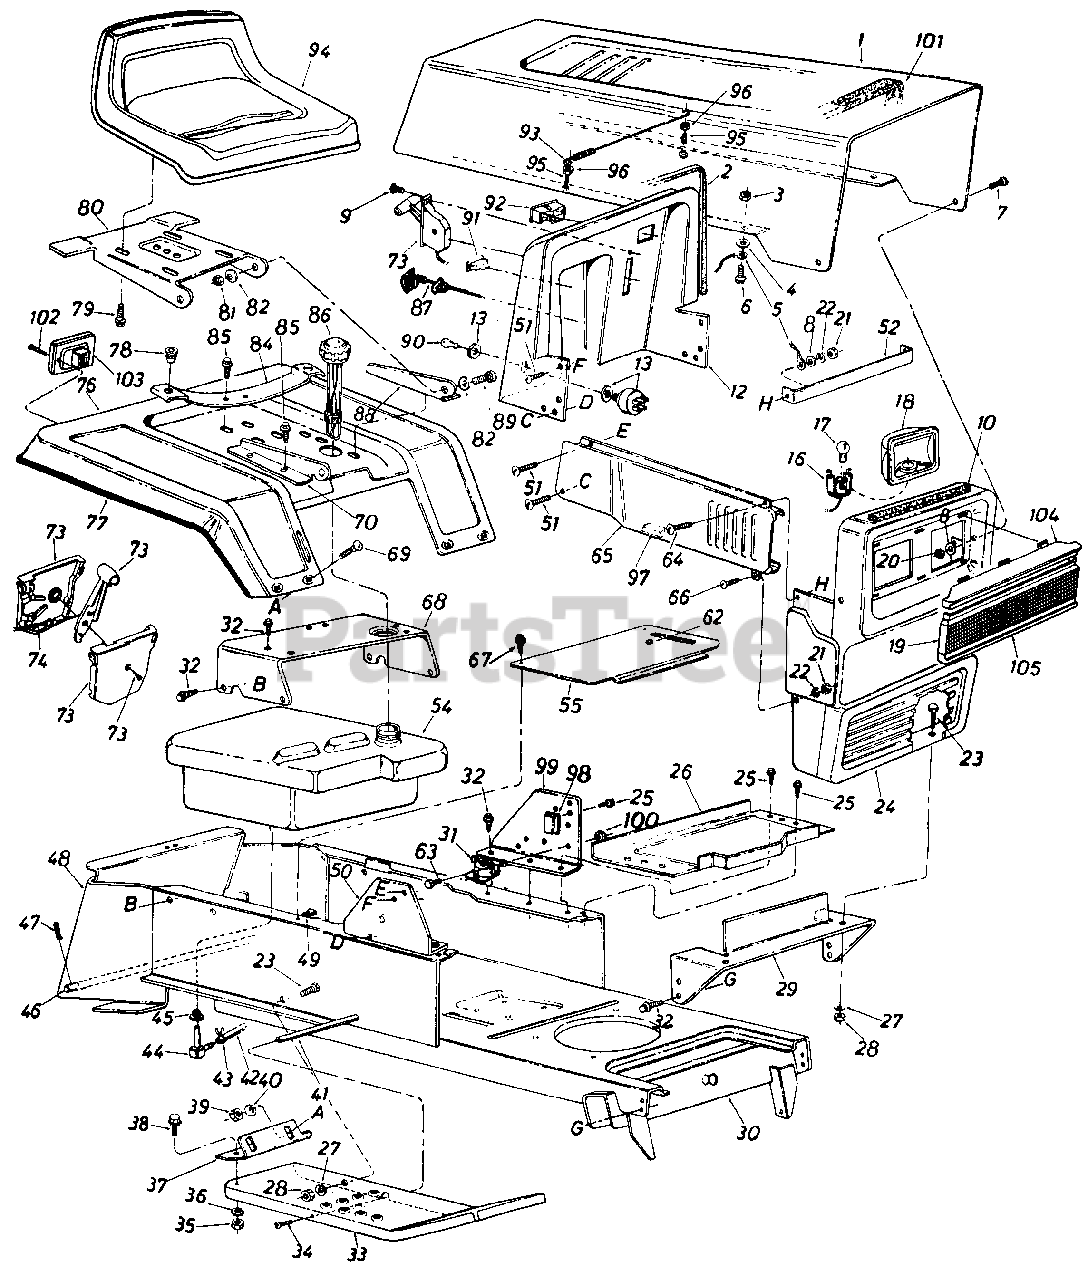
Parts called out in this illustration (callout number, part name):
1	Hood
2	Vinyl Molding Strip 29"
3	Hex Sems Nut #10-24 Thd.
4	Fl-Wash. .20" I.D. x .41" O.D.
5	Hood Stop
6	Truss Hd. Mach. Scr. #10-24 x.50" Lg.
7	Hex Bolt 1/4-20 x .62" Lg.
8	Fl-Wash. 1/4" I.D.
10	Foam Strip 3/8" x 1" x 14"
12	Dash Ass'y.
13	Ignition Switch
16	Socket
17	Lamp
18	Headlight Housing
19	Headlight Bezel
20	Hex L-Nut 1/4-20 Thd.
21	Hex Nut 1/4-20 Thd.
22	L-Wash. 1/4" I.D.
23	Hex Bolt 5/16-18 x .75" Lg.
24	Grille
25	Hex Wash. Hd. AB-Tap Scr. 1/4 x.50" Lg.
26	Battery Plate
27	L-Wash. 5/16" I.D.
28	Hex Nut 5/16-18 Thd.
29	Grille Mounting Bracket
30	Lower Frame Ass'y.
31	Solenoid
32	Hex Thd. Rolling Scr. 5/16-24 x .75" Lg.
33	Running Board R.H.
34	Truss Mach. Scr. 5/16-18 x .75" Lg.
35	Hex Nut 5/16-18 Thd.
36	Bell-Wash. .34" I.D.
39	Hex Nut 1/4-20 Thd.
40	L-Wash. 1/4" I.D.
41	Running Board Rod
42	Fuel Line 44" Lg.
43	Hose Clamp 3/8"
44	90ø Elbow
45	Bushing
46	Hitch Rod
47	Internal Cotter Pin
48	Hitch Plate
49	Speed Nut
50	Dash Support Brkt. R.H.
51	Hex Wash Hd. Tap Scr. 1/4 x .75" Lg.
52	Tie Strap Grille Side Panel
54	Fuel Tank
55	Transmission Cover Ass'y.
62	Snap Bushing
63	Hex Bolt 1/4-20 x .50" Lg.
64	Truss Hd. Scr. 1/4-20 x .75" Lg.
65	Side Panel R.H.
66	Truss Mach. Scr. /4-20 x .50" Lg.
67	Truss Mach. B-Tap Scr. #10 x.50" Lg.
68	Seat Mounting Channel
69	Carriage Bolt 1/4-20 x .50" Lg.
70	Seat Bracket R.H.
73	Throttle Control Box Ass'y.
74	Throttle Control Wire
76	Rear Fender
77	Trim Strip 81
78	Grommet
79	Hex Wash. Hd. AB-Tap Scr. 3/8 x .75" Lg .
80	Seat Pivot Bracket
81	Hex Cent. L-Nut 5/16-18 Thd.
82	Belleville Wash. .34" I.D. x .88" O.D.
84	Seat Spring
85	Hex Wash. Hd. Self-Tap Scr. 5/16-18 x .50" Lg.
86	Gas Cap w/Gauge
87	Choke Control Comp.
88	Seat Bracket L.H.
89	-Hex Bolt 5/16-18 x .75" Lg.
90	Ignition Key
91	Light Switch
92	Ammeter
93	Hood Spring
94	Seat Ass'y.
95	Hex Bolt #10-24 x 1.0" Lg.
96	Hex Sems Nut #10-24
97	Rubber Strip 1/2" Sq. x 2-1/2" Lg.
98	Circuit Breaker
99	Dash Support Brkt. L.H.
100	Hex Sems Nut 1/4-20 Thd.
101	PVC Foam
102	Truss Hd. AB-Tap Scr. #6 x .62" Lg.
103	Taillight
104	Upper Frame For Bezel
105	Lower Frame For Bezel
